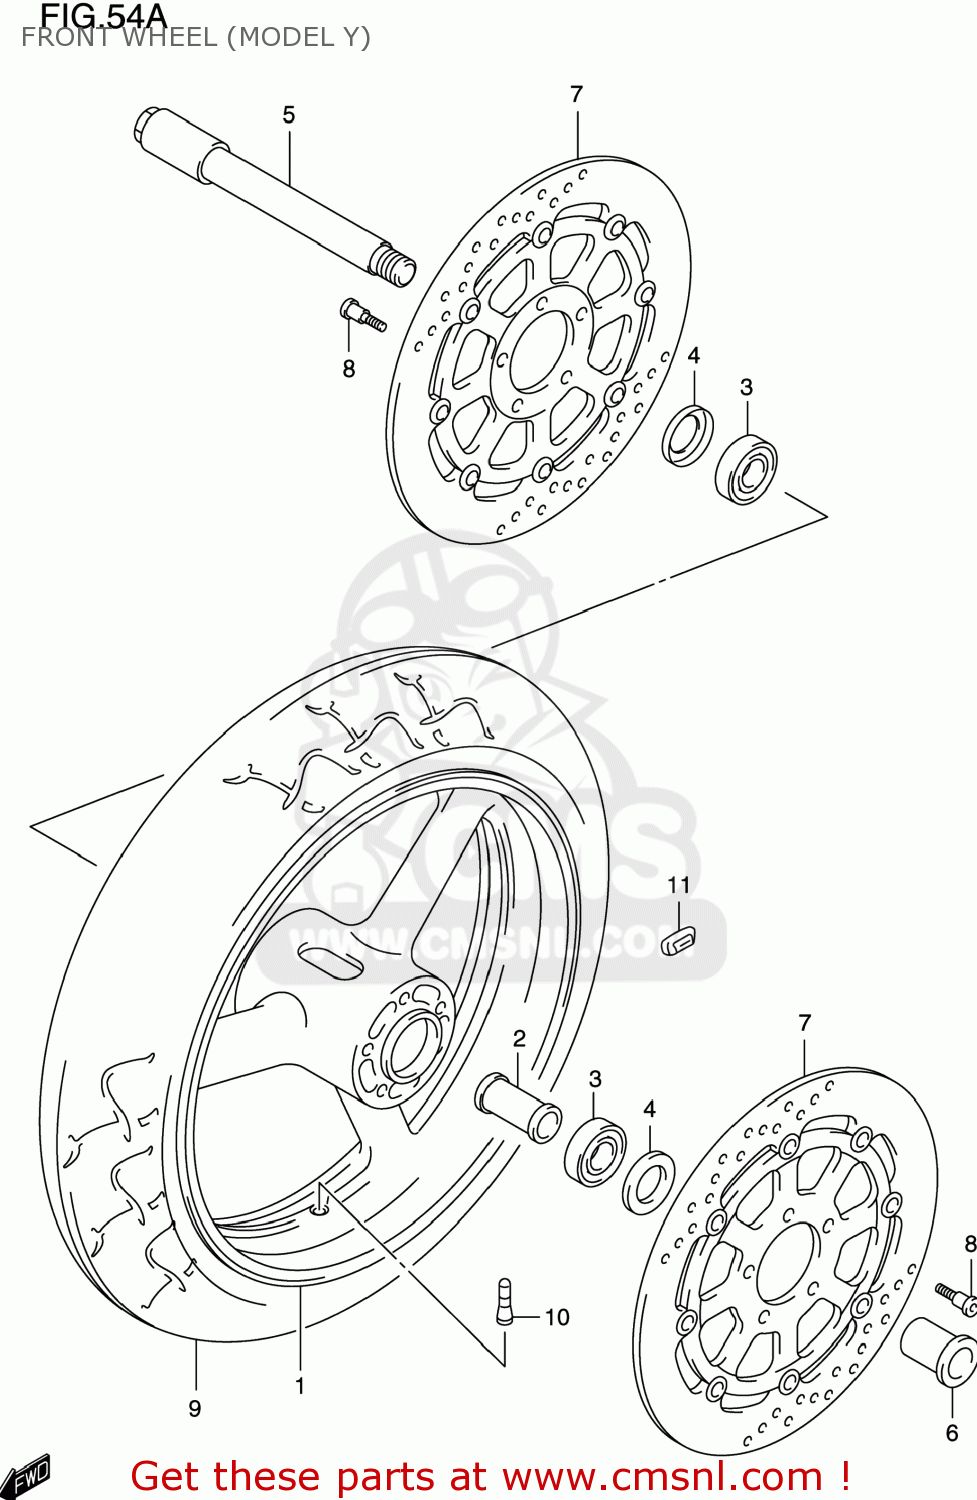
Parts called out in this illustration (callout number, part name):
1	WHEEL,FRONT (17XMT3.50)(
2	SPACER,FR HUB BEARING
3	BEARING(25X52X15)
4	SEAL,OIL(32X52X7)
5	AXLE,FR
6	NUT,FR AXLE
7	DISC,FR BRAKE
8	BOLT 8X33
9	TIRE,FRONT 120/70 ZR17
10	VALVE ASSY,WHEEL RIM(TR412)
11	BALANCER,WHEEL (10G)
